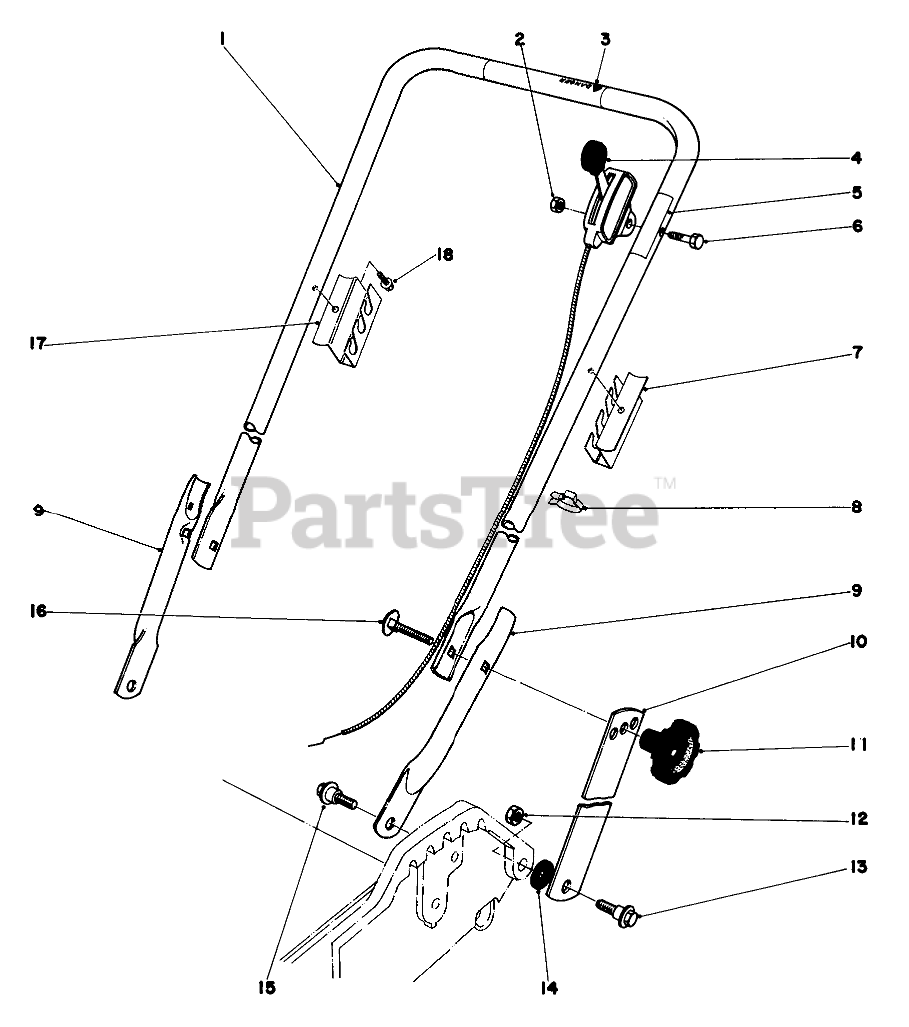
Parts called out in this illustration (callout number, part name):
1	Handle-Upper
2	NUT-LOCK
3	Decal-Danger
4	Throttle Control
5	Decal-Throttle (Swedish)
6	SCREW-HH
7	SUPPORT BAG LH
8	BOWDEN CLIP
9	Hand-Lower
10	18" HANDLE LATCH
12	Nut
13	SCREW-SHOULDER
14	SPACER
15	SCREW-SHOULDER
16	SCREW-HANDLE
17	SUPPORT BAG RH
18	SCREW-HWHTF
